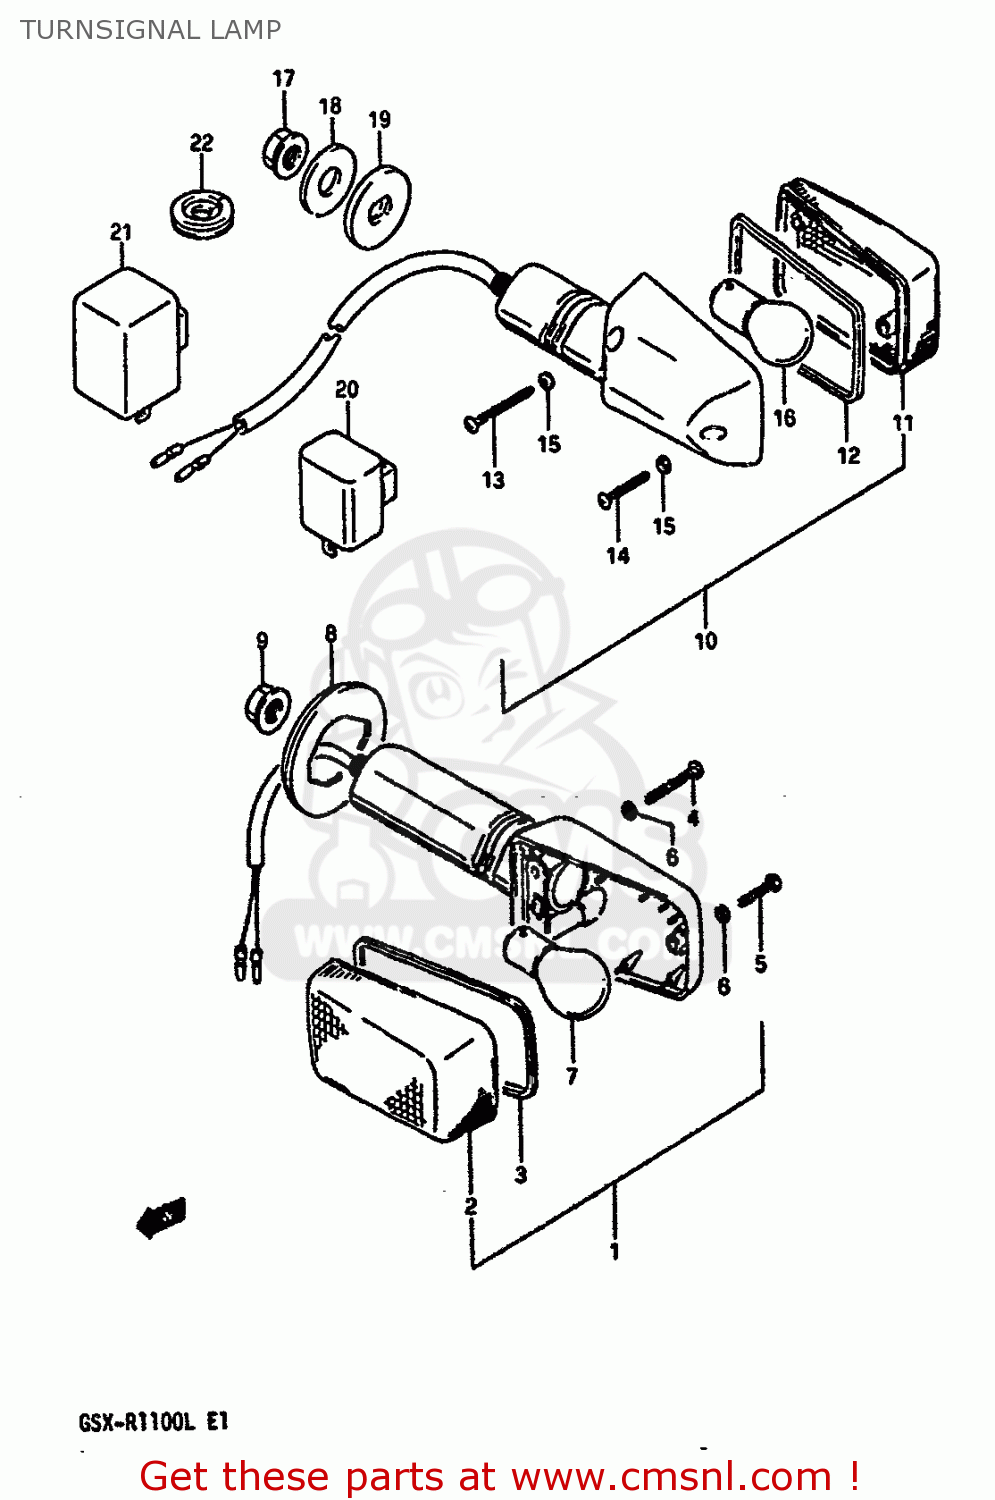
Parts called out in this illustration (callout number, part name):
1	LAMP ASSEMBLY,FRONT TURN SIGNAL
2	LENS
3	GASKET (NAS)
4	SCREW(3X30)
5	SCREW
6	GASKET (NAS)
7	BULB(12V21W)
8	GROMMET
9	NUT
10	LAMP ASSY,RR TURNSIGNAL
11	LENS
12	GASKET (NAS)
13	SCREW(3X30)
14	SCREW
15	GASKET (NAS)
16	BULB(12V21W)
17	NUT
18	WASHER(10.5X30X3.2)
19	SPACER,RR TURNSIGNAL
20	RELAY ASSEMBLY,TURN SIGNAL
21	RELAY ASSY,TUR
22	GROMMET
